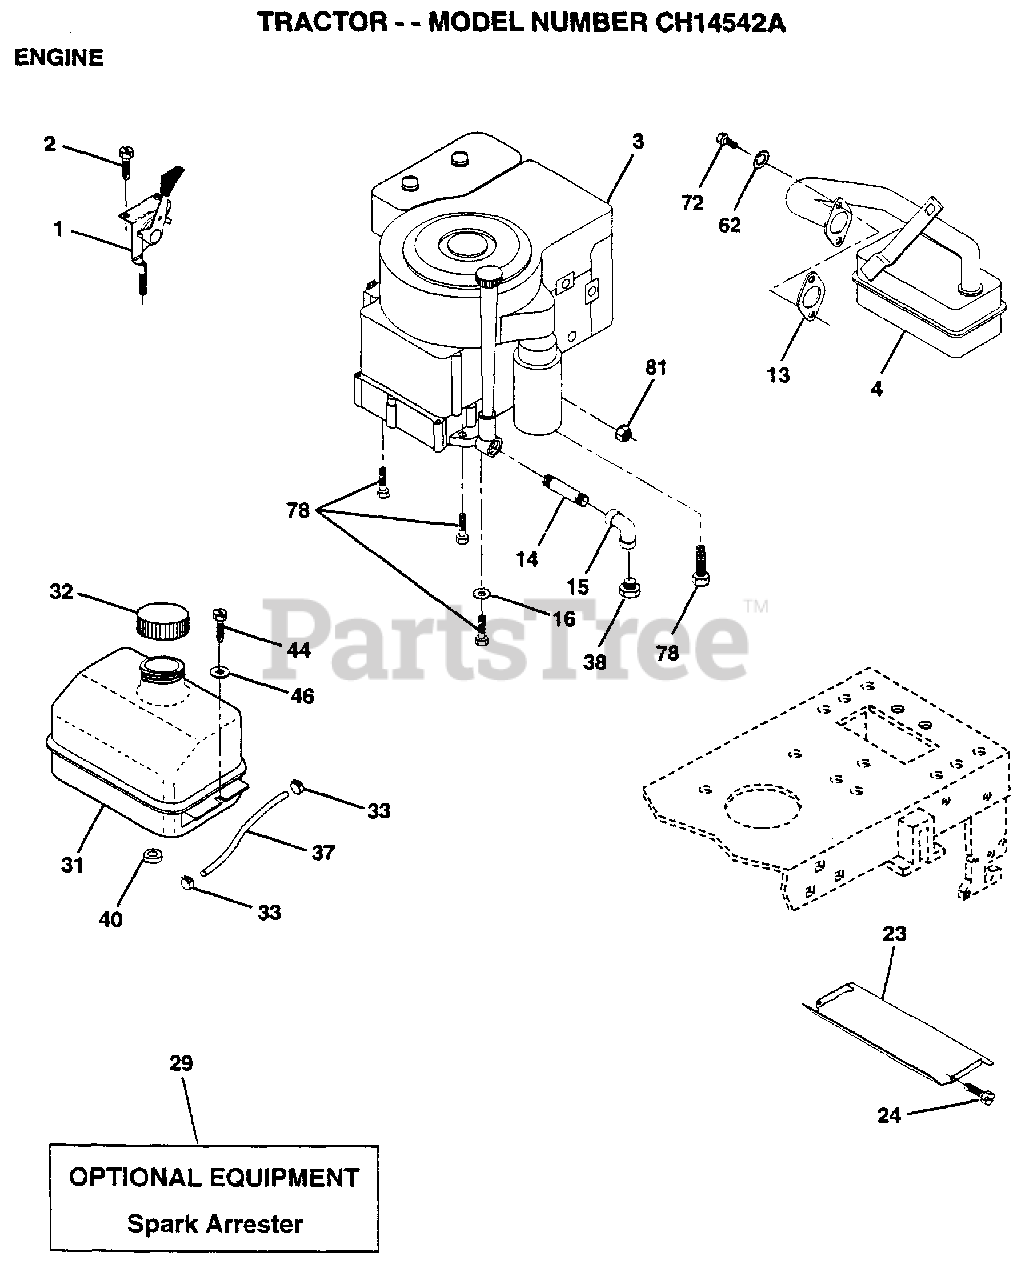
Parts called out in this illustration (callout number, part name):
1	THROTTLE CONTROL
2	SCREW LT
4	MUFFLER
13	GASKET ENG 1 313 LD TIN PLATED
14	PIPE NIPPLE
15	ELBOW
16	LOCKWASHER
23	HEAT SHIELD
24	SCREW
31	TANK.FUEL.LT.
32	CAP ASM FUEL
33	HOSE CLAMP
37	LINE FUEL
44	SCREW HEX CRT
46	WASHER
62	LOCKWASHER
72	SCREW
78	SCREW
81	NUT
